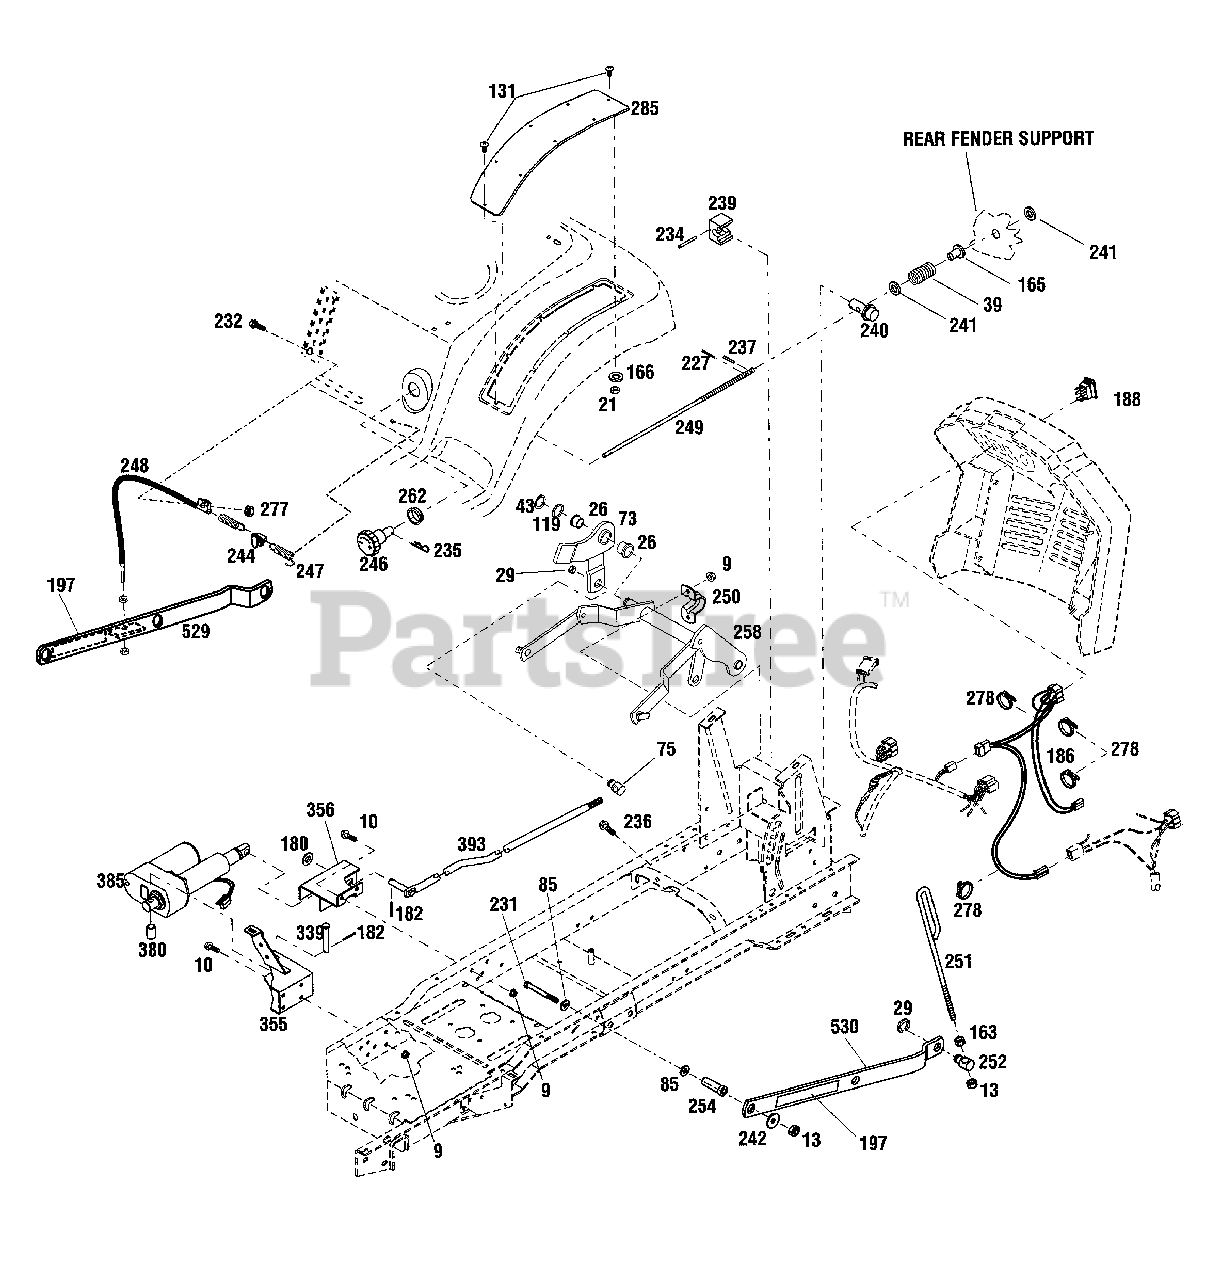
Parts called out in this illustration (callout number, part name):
9	Flange Nut, 5/16-18
10	Hex Head Screw, 5/16-18 x 3/4
13	Hex Top Locknut 3/8-16
21	Nylon Locknut, 1/4-20
26	Flange Bushing
29	E-Ring, 5/8
39	Compression spring
43	Retaining Ring
73	Pivot Arm Assembly
75	Pivot Block
85	Flat Washer, 3/8
119	Flat Washer 1-1/64
131	Screw, 1/4-20 x 5/8
163	Hex Nut, 3/8-18
165	Nyliner Bushing
166	Flat Washer, 1/4
180	Flat Washer, 1/2
182	Cotter Pin, 1/4 x 1
186	Actuator Harness
188	Rocker Switch
197	Warning Decal
227	Cotter Pin, 1/8 x 3/4
231	Hex Head Screw, 3/8-16 x 3
232	Screw, 10-24 x 5/16
234	Drive Pin
235	Hitch Pin
236	Flange Screw 5/16-18 x 3/4
237	Drive Pin
239	Height Adjust Collar
240	Height Adjust Block
241	Flat Washer, 1/2 x 1
242	Flat Washer, 3/8 x 1-1/2
244	Height Indicator
246	Height Adjust Knob
247	Extension Spring
248	Cable Assembly
249	Height Adjust Screw
250	Lift Clamp
252	Rear Lift Swivel
254	Spacer
258	Lift Assembly
262	Snap Bushing Grommet
277	Keps Nut,10-24
278	Cable Tie
339	Clevis Pin, 1/2
355	Front Support
356	Rear Support
529	Lift Link Assembly RH
530	Lift Link Assembly LH
